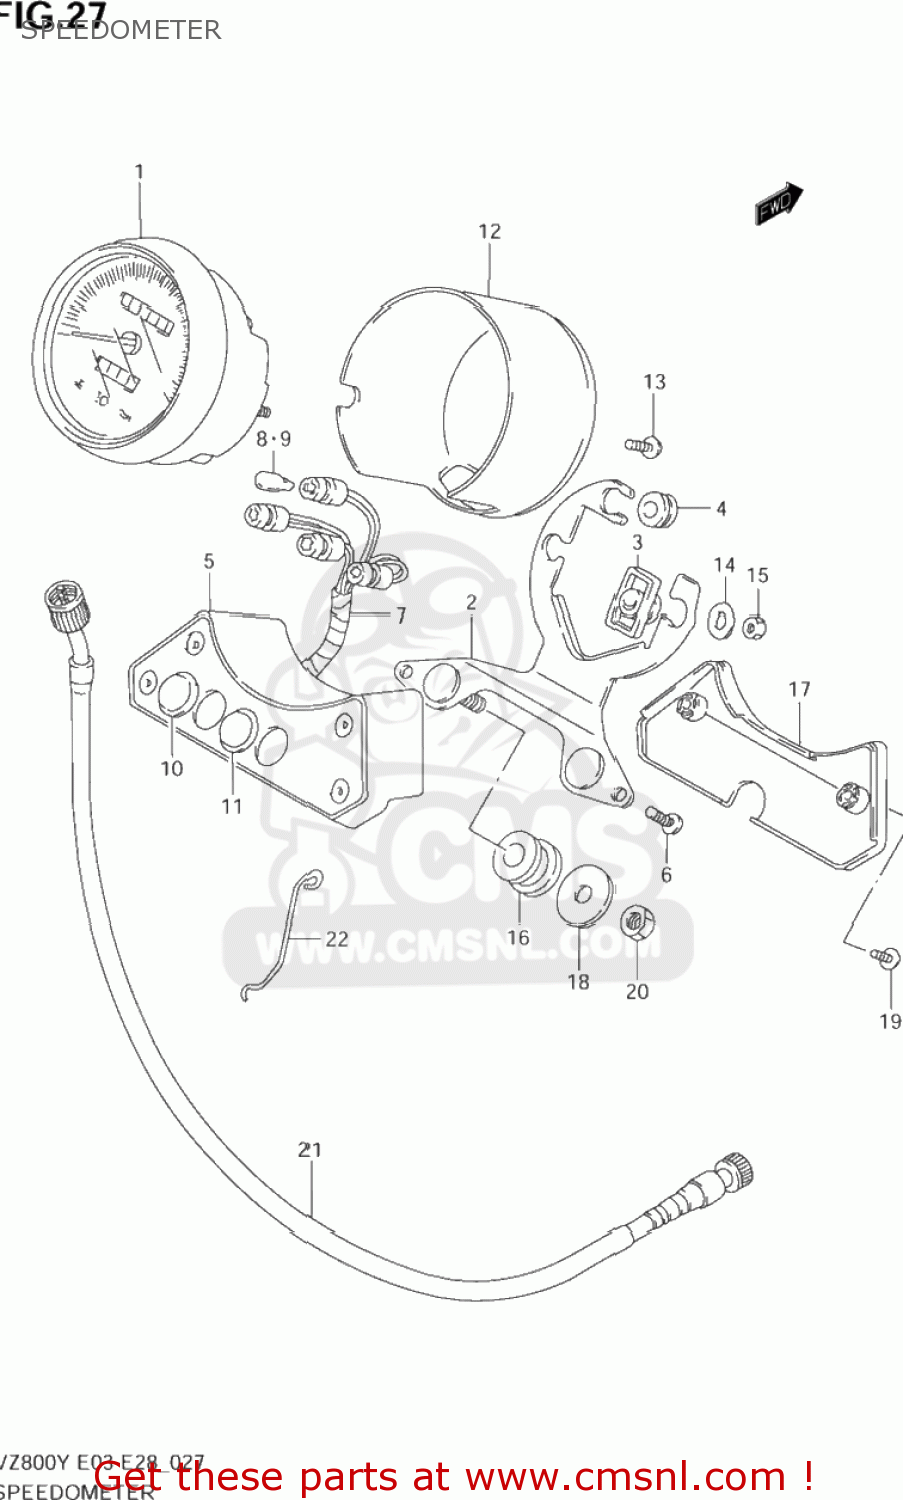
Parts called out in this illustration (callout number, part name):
1	SPEEDOMETER
2	BRACKET
3	CUSHION,DAMPER
4	DAMPER
5	CASE ASSY,PILOT
6	SCREW
7	CORD ASSY
8	BULB(12V1.7W,T6.5)
9	BULB(12V3.4W,T10)
10	LENS(GREEN)
11	LENS,TURNSIGNAL(GREEN)
12	COVER,UNDER(CHROMUN)
13	SCREW
14	WASHER(5.2X16X1)
15	NUT
16	CUSHION,METER BRACKET
17	COVER,P-BOX
18	WASHER(8.5X28X1.6)
19	SCREW
20	NUT
21	CABLE ASSY,SPEEDOMETER
22	GUIDE,SPEEDOMETER CABLE
